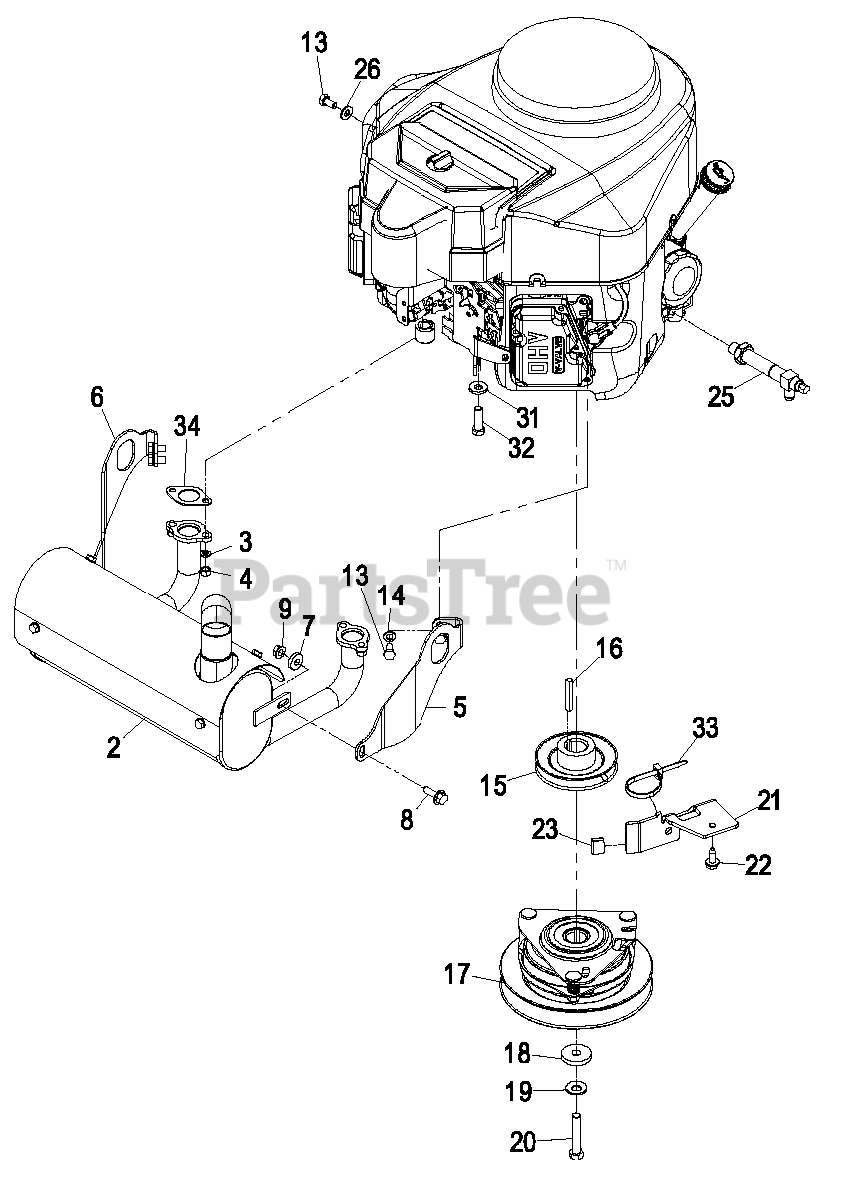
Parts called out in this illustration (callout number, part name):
3	WASHER-LOCK
5	BRACKET-MUFFLER MOUNT, LH
6	BRACKET-MUFFLER MOUNT, RH
8	SCREW-HHF
13	SCREW-HH
14	WASHER-LOCK
16	KEY-SQUARE
17	CLUTCH / BRAKE ASM
18	WASHER
19	WASHER-SPRING
20	SCREW-HH
22	Screw-HWH 5/16-18 X 3/4 Tf
26	WASHER-PLAIN
31	WASHER-BELLEVILLE
32	SCREW-HH
33	TIE-CABLE
34	GASKET-EXHAUST
